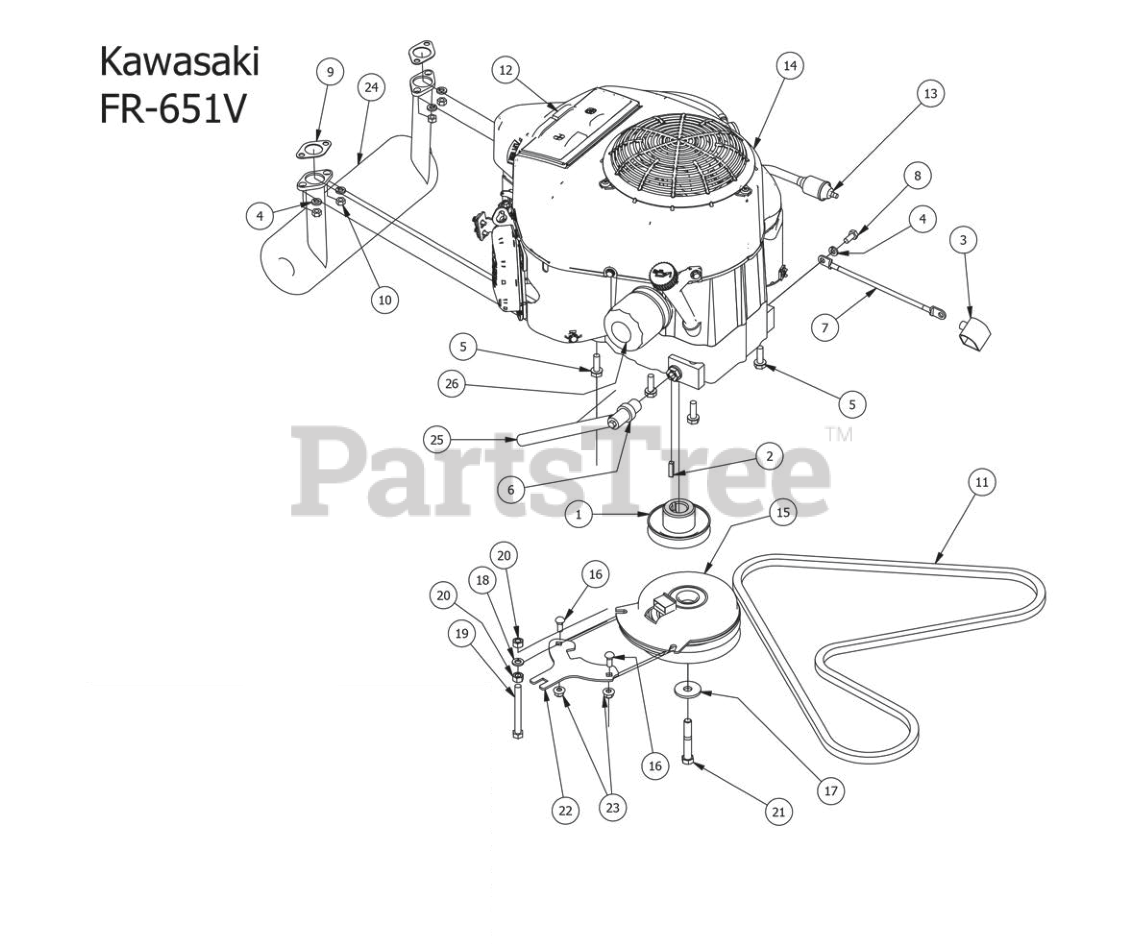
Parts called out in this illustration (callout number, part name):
1	3-3/4" Motor Pulley
2	1/4" x 1" Key
3	Black Boot For ground cable
4	5/16" Lock Washer
5	3/8 x 1 1/8 bolt
7	Ground Cable
8	M8x1.20x20MM Hex head bolt
9	Exhaust gasket
10	M8-1.25 Zinc Nut
12	Kaw air Filter For Engine
13	Universal inline Fuel Filter
14	726cc Kawasaki Engine-FR651V
15	MZ Clutch Assembly
16	5/16-18x3/4 carriage bolt
17	1/2 Belleville Washer
18	3/8" Lock Washer
19	3/8-16x3-1/2 grade 5 hex bolt
20	3/8" Hex Nut
21	7/16x2 3/4 Fine Thread Bolt
22	MZ Clutch Holder
23	5/16" Nylon Flange Nut
24	Exhaust for FR Kawasaki-MZ
25	1/2 Clear Braded Hose Priced/Foot
26	Kaw Oil Filter FR Engine
